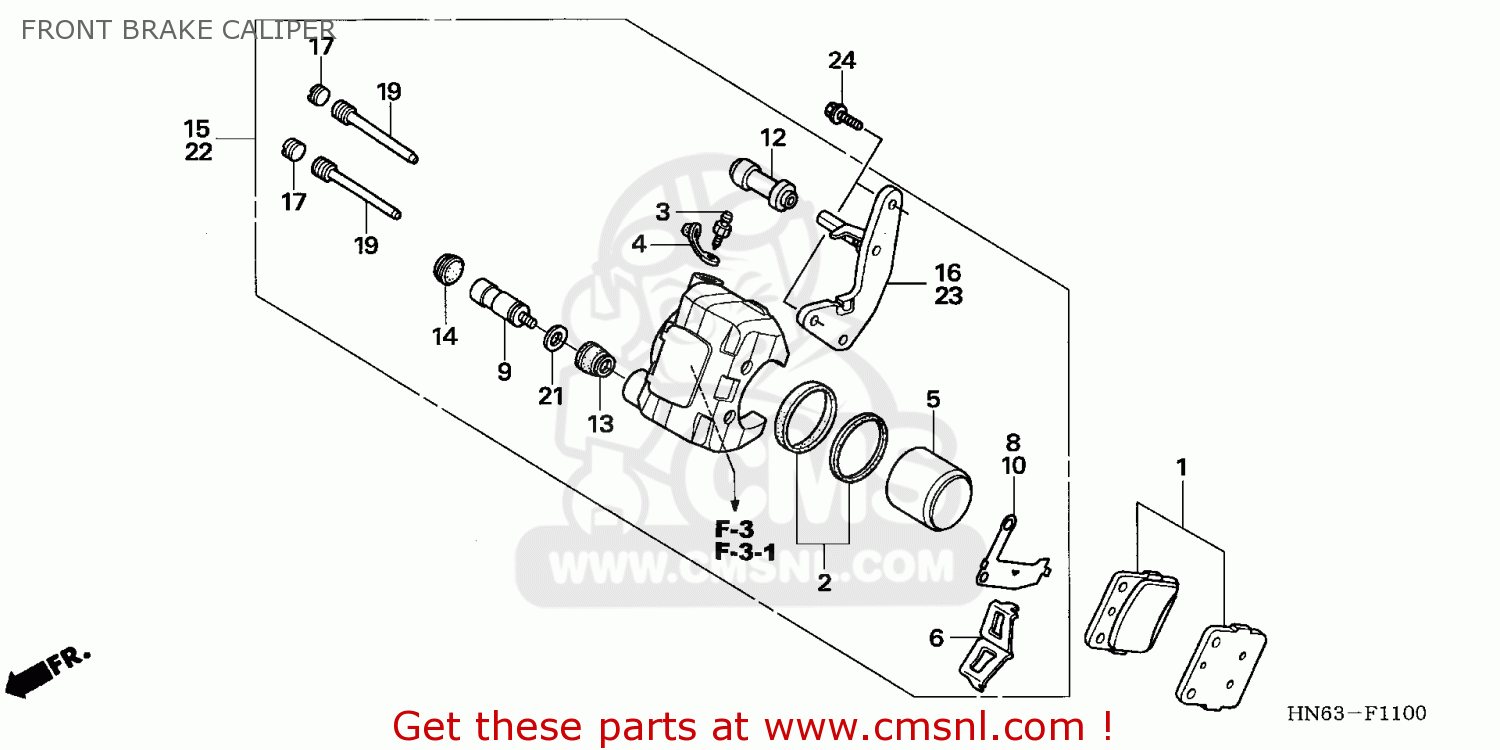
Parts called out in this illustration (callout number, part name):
1	PAD SET,RR BRAKE (NAS)
2	SEAL SET,PISTON
3	SCREW, BLEEDER
4	CAP,BLEEDER
5	PISTON COMP.
6	SPRING,PAD
8	SHIM,L.
9	PIN,SLIDE
10	SHIM,R.
12	BUSH,PIN
13	BOOT,PIN
14	DUST PLUG
15	CALIPER SUB ASSY,
16	BRKT SUB ASSY,FR
17	PLUG,PIN
19	HANGER PIN
21	WASH,CONICAL SPG
22	CALIPER SUB ASSY,
23	BRKT SUB ASSY,FR
24	BOLT,FLANGE,8X20
